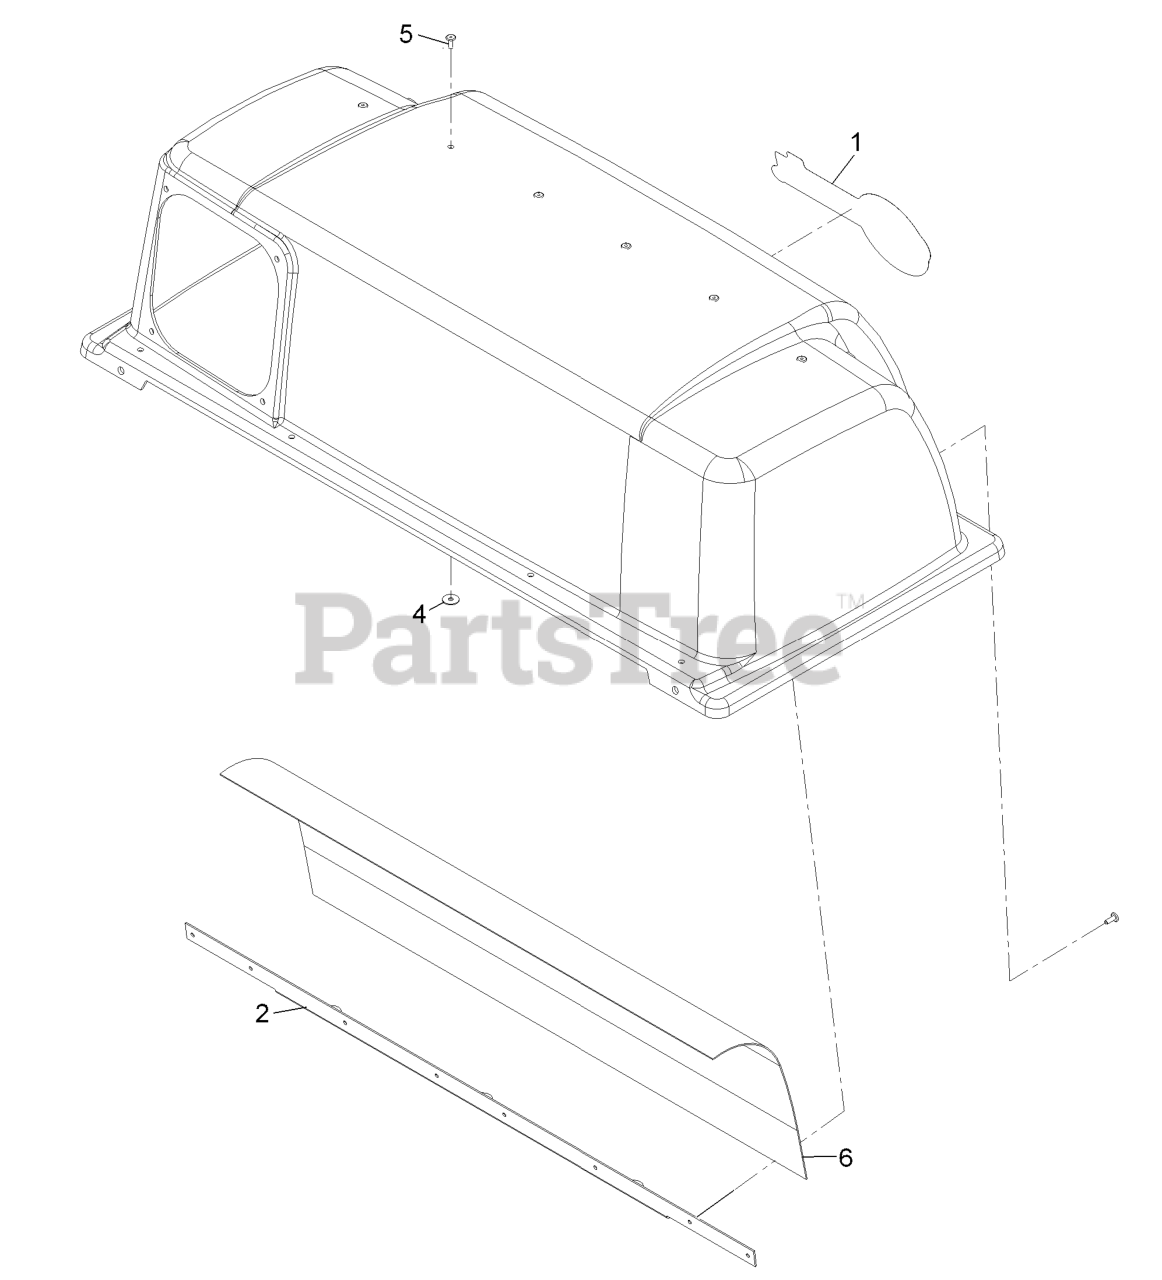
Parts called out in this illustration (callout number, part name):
1	DECAL, EXMARK LOGO
2	SUPPORT-SCREEN
4	WASHER-FLAT
5	RIVET-BLIND
6	SCREEN-BAGGER
